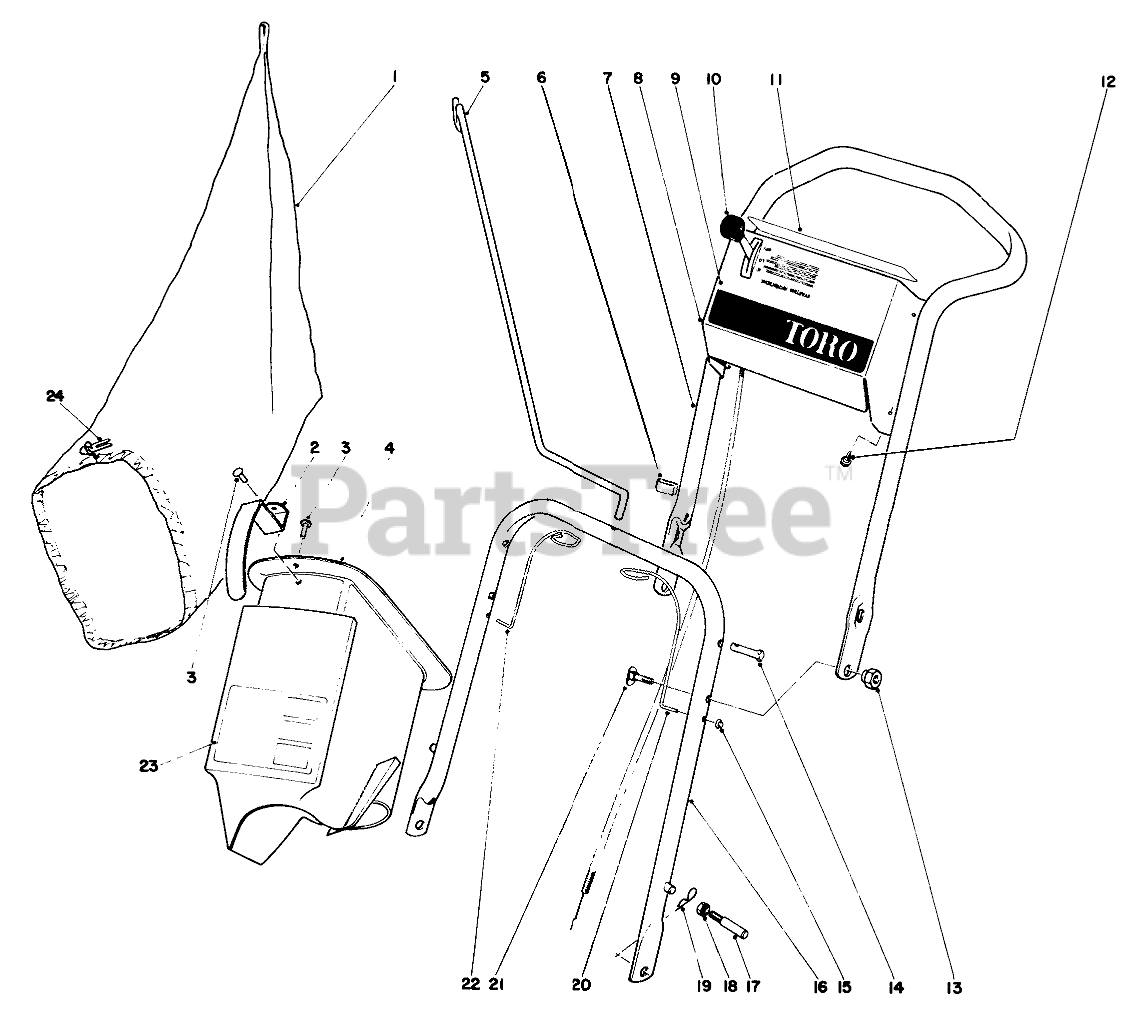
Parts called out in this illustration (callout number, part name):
1	Grass Bag (Incl. Ref. No. 24)
2	HANDLE-GRASS CHUTE
3	Rivet
4	Grass Chute Assembly (Incl. Ref. No. 2-3 & 23)
5	Bag Rod
7	Upper Handle
8	Control Plate
9	Decal Control Plate
10	Control Throttle
11	Decal, Safety
12	SCREW-HWHTF
13	Pivot Nut
14	Latch Pin
16	Lower Handle
17	HANDLE PIN
18	Nut
19	PIN-COTTER, HAIR
20	Latch Spring L.H.
21	HANDLE SCREW
22	Latch Spring R.H.
23	Decal Instructions
24	BAG CORD FASTENER
